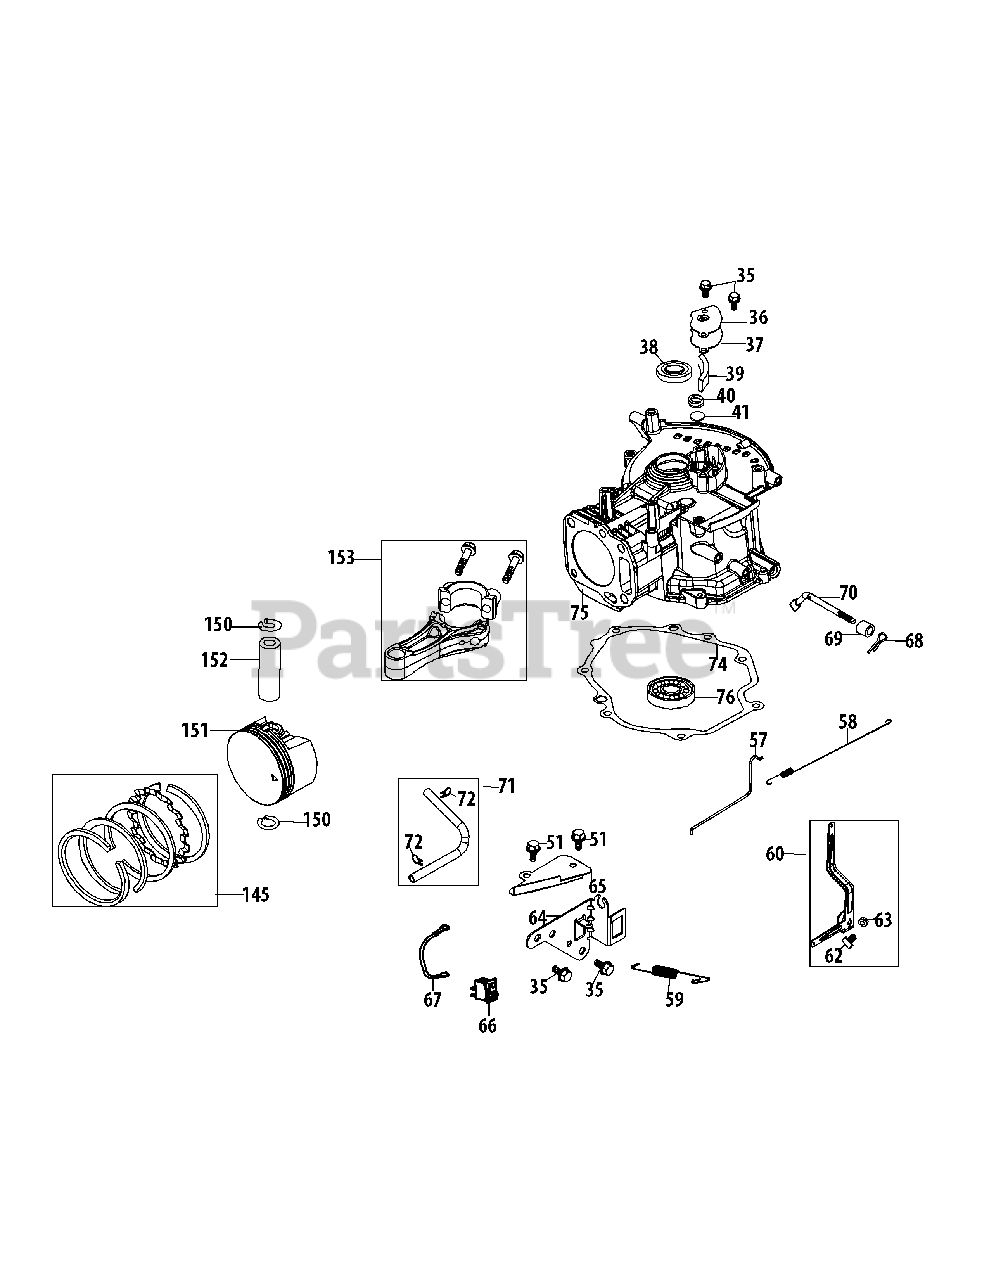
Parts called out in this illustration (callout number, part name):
35	BOLT M6-1 x 14 GR8.8
36	BREATHER COVER PLATE
37	BREATHER GASKET
38	CRANKSHAFT SEAL
39	BREATHER SCREEN
40	BREATHER VALVE SPRING
41	BREATHER VALVE
51	BOLT M6-1 x 12 GR8.8
57	THROTTLE LINKAGE
58	THROTTLE LINKAGE SPRING
59	GOVERNOR SPRING
60	GOVERNOR ARM ASSEMBLY
62	BOLT M6-1 x 21
64	COMPONENT BRACKET
65	AIR VANE COVER PLATE
66	IGNITION SWITCH
67	IGNITION SWITCH
68	COTTER PIN
69	GOVERNOR SEAL
70	GOVERNOR ARM SHAFT
71	BREATHER HOSE
72	BREATHER HOSE CLAMP
74	CRANKCASE COVER GASKET
75	CRANKCASE
145	PISTON RING SET
150	SNAP RING-PISTON PIN
151	PISTON
152	PISTON PIN
153	CONNECTING ROD ASSEMBLY
